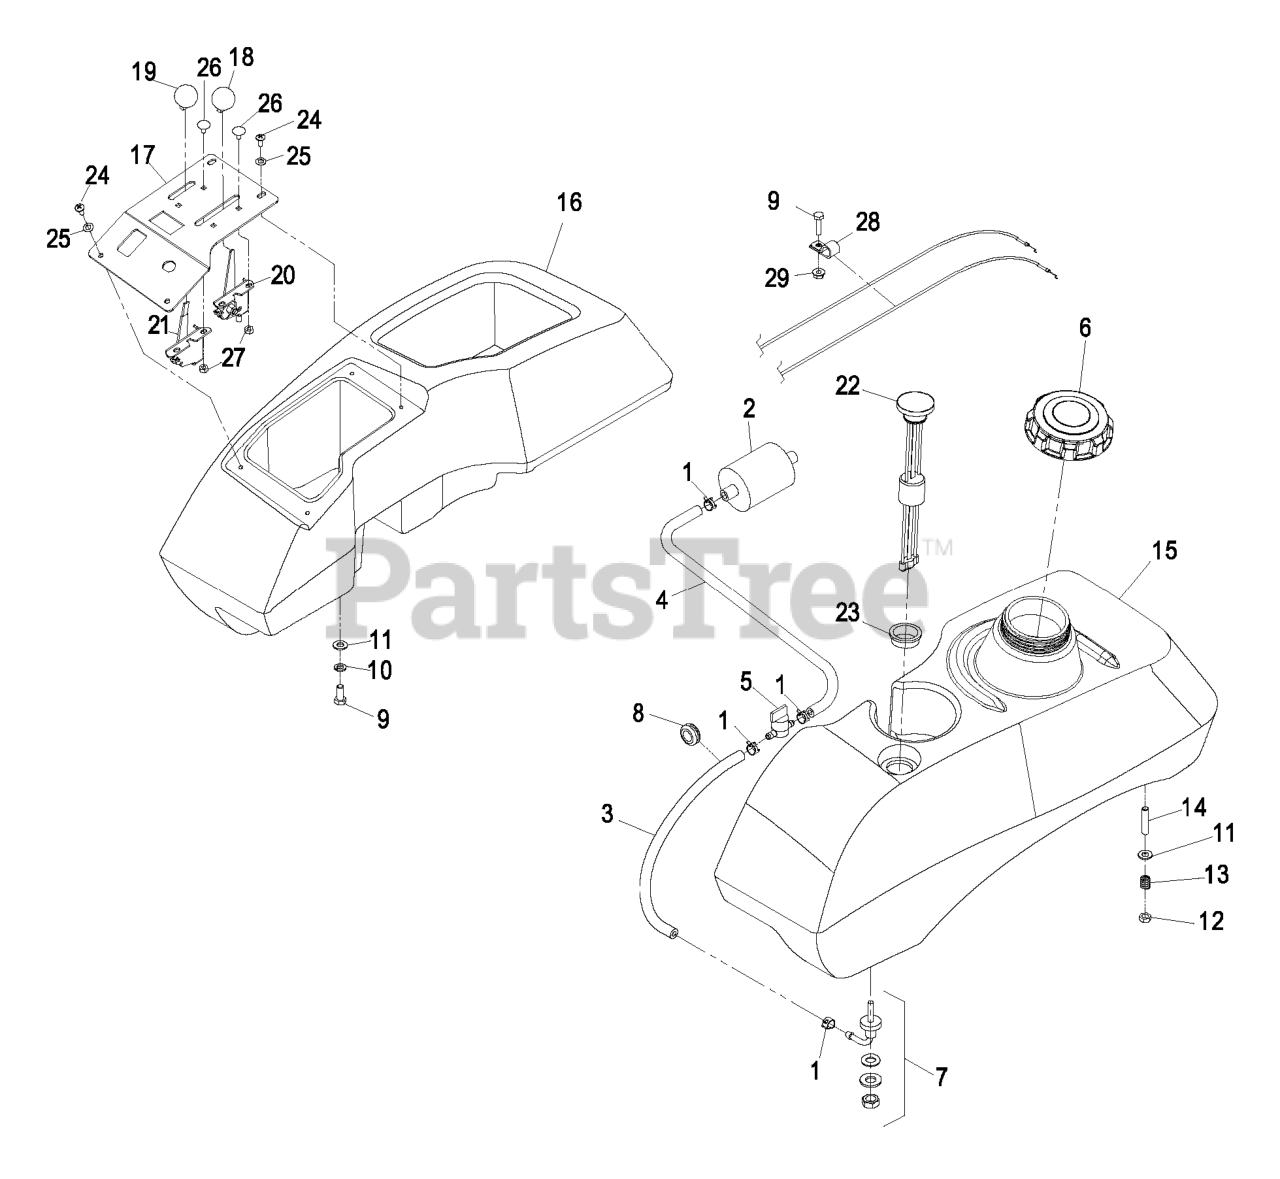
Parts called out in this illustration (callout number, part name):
2	Fuel Filter "Briggs & Stratton"
3	HOSE-FUEL
4	HOSE-FUEL
5	VALVE-FUEL
6	CAP-FUEL, GAS
7	FITTING-FUEL, BULKHEAD
8	GROMMET
9	SCREW-HH
10	WASHER-LOCK
11	WASHER-PLAIN
12	NUT-LOCK, NI
13	SPRING-TANK, FUEL
14	STUD
15	KIT,FUEL TANK LH LCT
16	ASM, TANK RH LCT S.O.
18	KNOB-BALL
19	KNOB-BALL, BLACK
20	CONTROL-THROTTLE
21	CABLE-THROTTLE
23	CONTACT ORDER SERVICES
24	SCREW-PPH
25	WASHER-SPRING
26	BOLT-CARR
27	NUT-LOCK, NI
28	CLIP-LOOM
